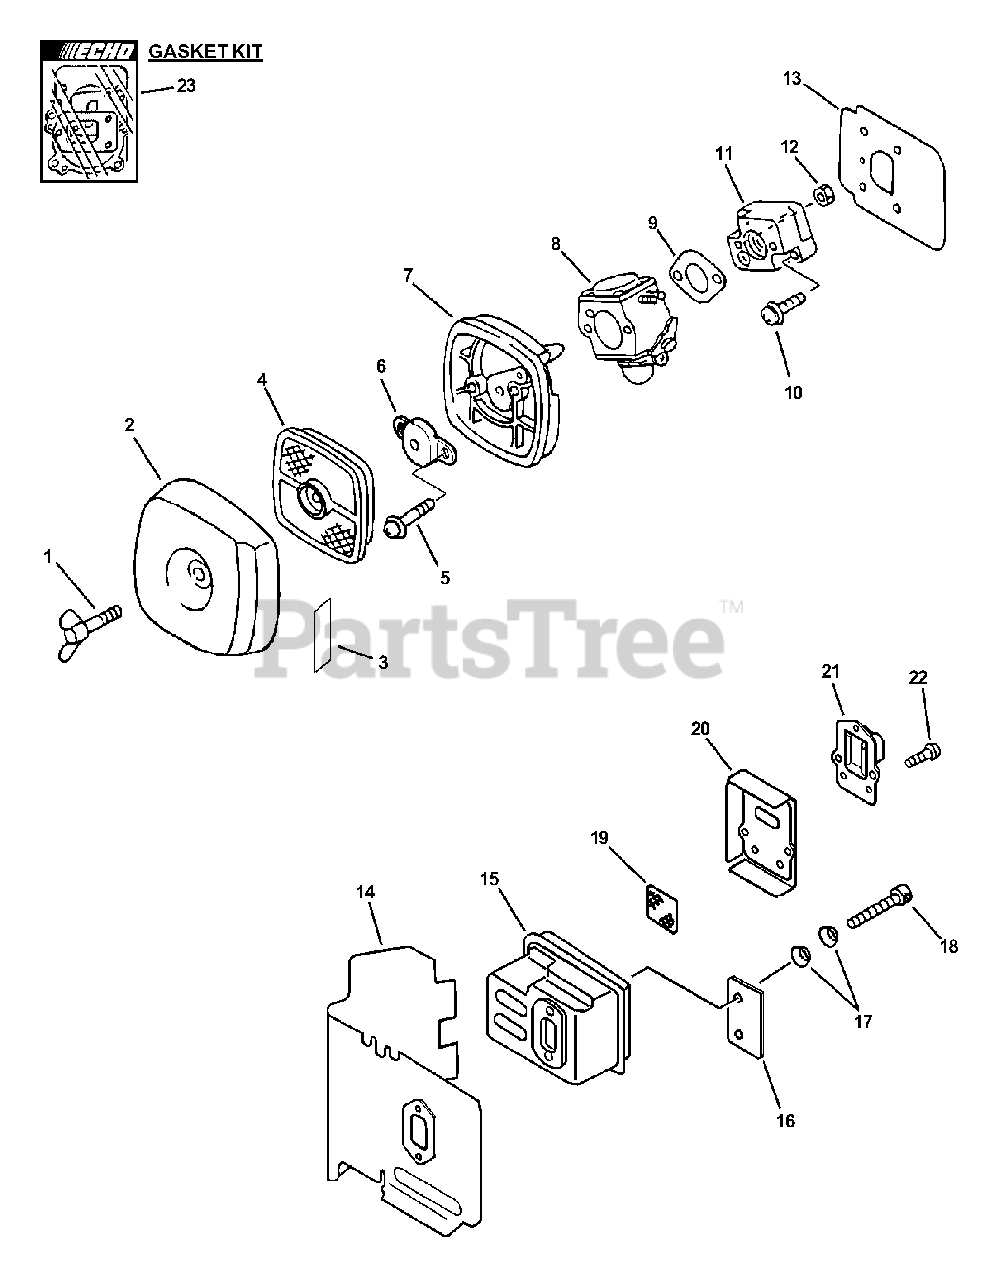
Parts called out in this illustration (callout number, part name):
1	THUMBSCREW
2	COVER, AIR FILTER - GRAY
3	LABEL - CHOKE
4	FILTER, AIR - SINGLE LAYER
5	SCREW - 5X65
6	PLATE, PREVENT
7	CASE, AIR FILTER - GRAY
8	CARBURETOR C1U-K58
9	GASKET, INTAKE
10	SCREW - 5X20
11	INSULATOR, INTAKE
13	SHIELD, INTAKE
14	SHIELD, EXHAUST
15	MUFFLER
17	WASHER - CONICAL
18	SCREW - 5X55
19	SCREEN, SPARK ARRESTOR
20	GASKET, EXHAUST
21	GUIDE, EXHAUST
22	SCREW - 4X10
23	GASKET KIT
